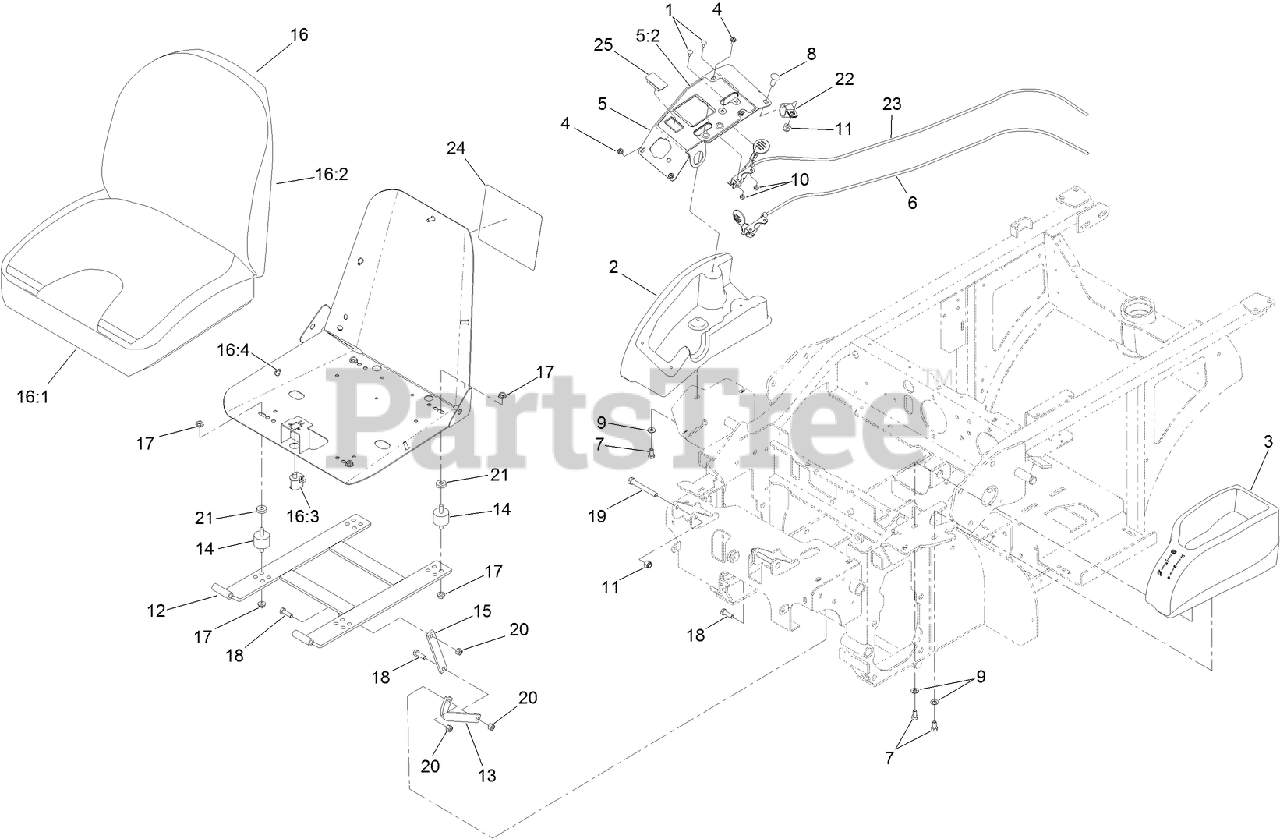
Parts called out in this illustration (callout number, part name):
1	BOLT-CARR
2	CONSOLE-RH
3	CONSOLE-LH
4	SCREW-PPH
5	CONTROL PANEL ASM
5:2	DECAL-CONTROL
6	CABLE-THROTTLE
7	SCREW-HH
8	SCREW-CARR
9	WASHER-PLAIN
10	NUT-LOCK, NI
11	NUT-LOCK, NI
12	FRAME-SEAT
13	LINK-SEAT STOP
14	MOUNT-VIBRATION, RUBBER
15	LINK-SEAT
16	SEAT ASM
16:1	CUSHION-SEAT, BOTTOM
16:2	CUSHION-SEAT, BACK
16:3	SWITCH-BAIL
16:4	BOLT-SEAT
17	NUT-HF
18	SCREW-HH
19	SCREW-HH
20	NUT-LOCK, NI
21	SPACER
22	CLIP-LOOM
23	CABLE-CHOKE
24	DECAL-SERVICE AID
25	PLUG-HOLE
